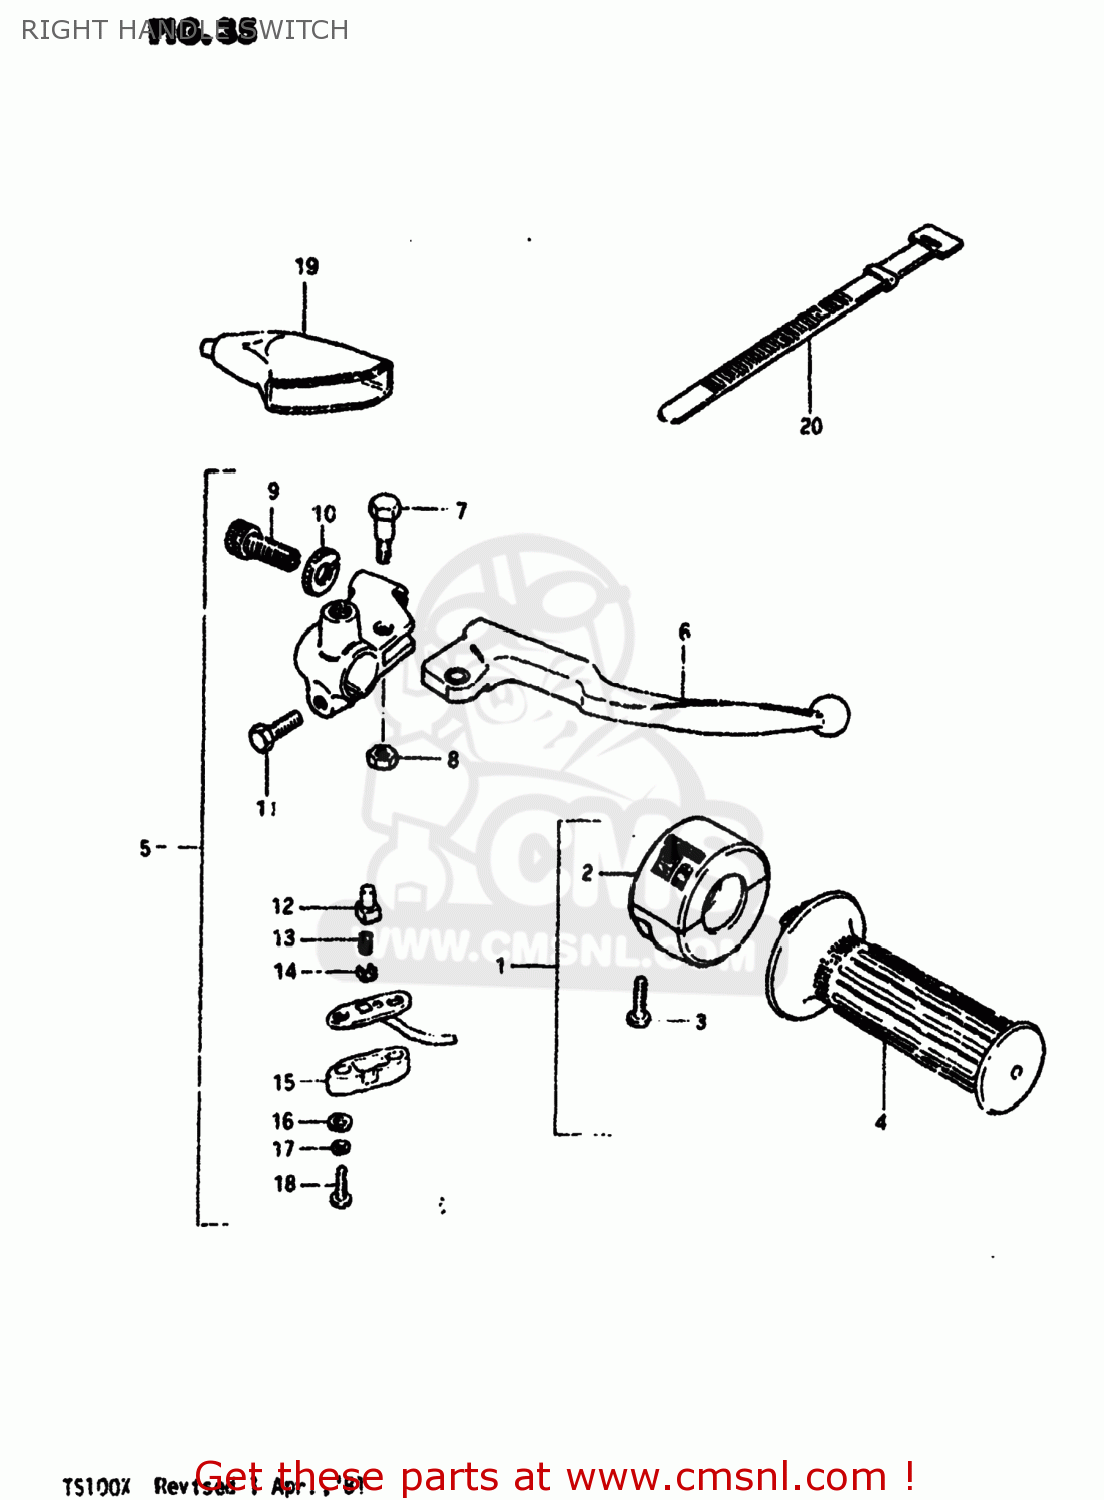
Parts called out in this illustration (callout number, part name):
1	CASE ASSEMBLY,THROTTLE
2	CASE ASSY,THROTTLE
3	SCREW
4	GRIP,THROTTLE
5	LEVER ASSY,BRAKE
6	LEVER,BRAKE
7	BOLT,LEVER
8	NUT 6MM
9	ADJUSTER,CABLE
10	NUT,CABLE ADJUSTER
11	BOLT
12	HOLDER
13	SPRING
14	PLATE
15	COVER,FR BK TERMINAL BASE
16	WASHER
17	LOCK WASHER
18	SCREW
19	COVER,CLUTCH LEVER
20	CLAMP(L:120)
